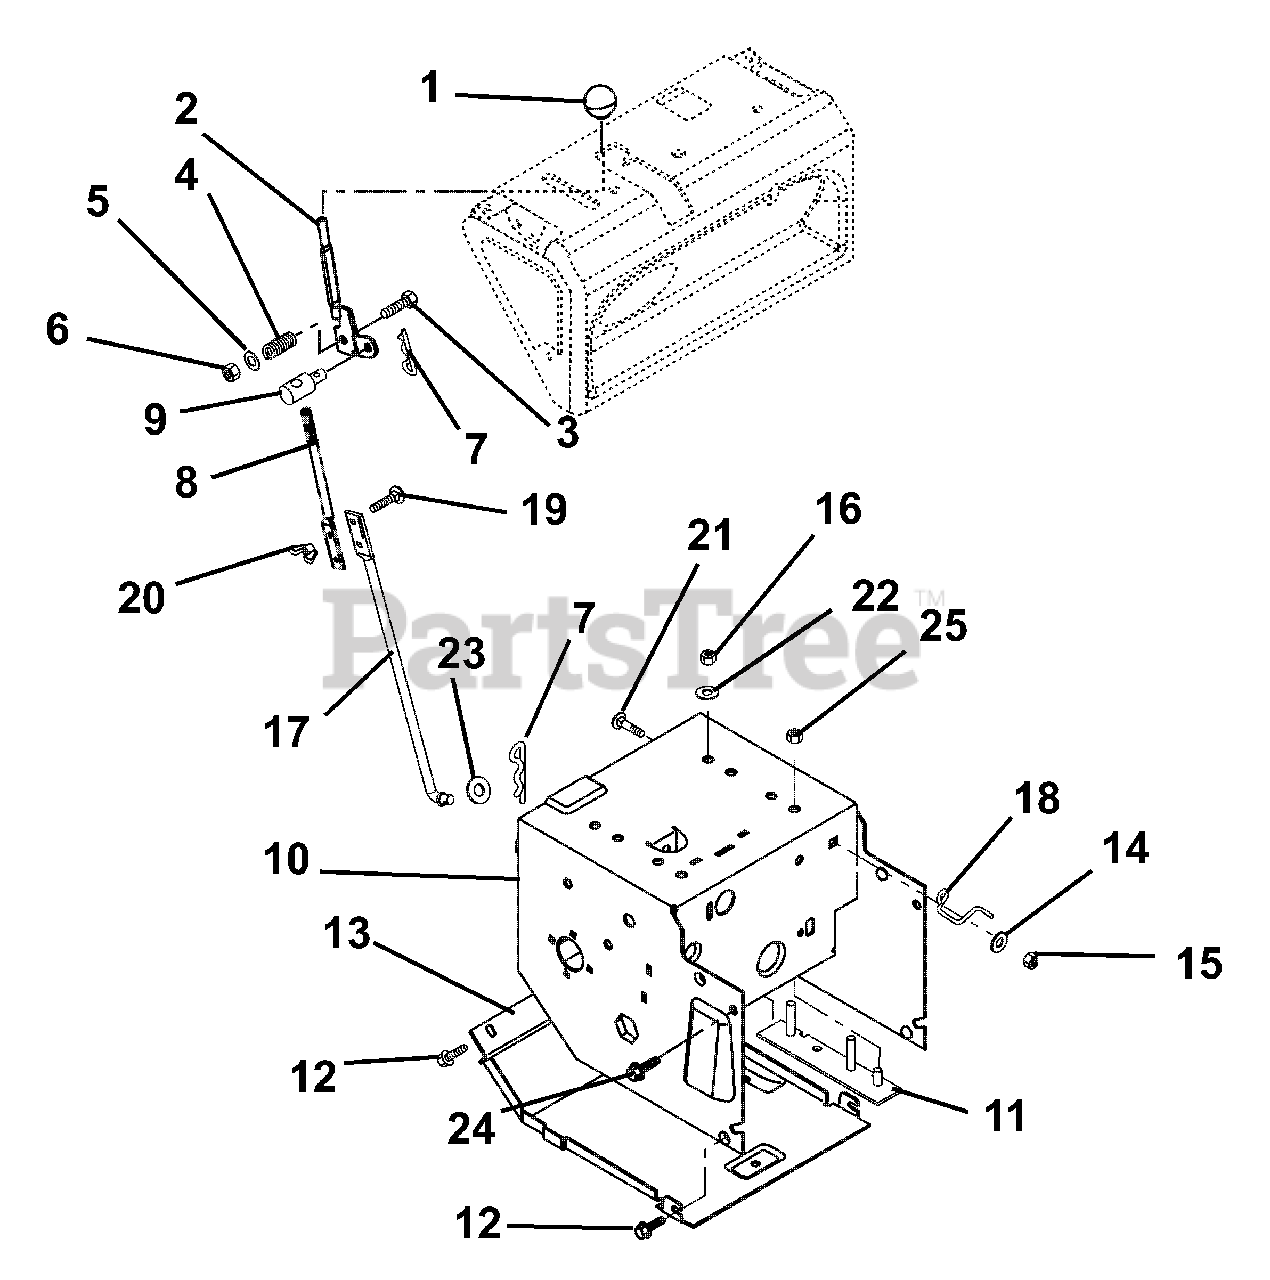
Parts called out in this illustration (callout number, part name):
1	KNOB,BALL -BLACK 1.47" .375-16
2	WMT, SHIFT LEVER
3	@BLT-RDHDSQNK .38-16X2.50 G5YZ
4	SG-COMP .125X.781X1.250
5	@WSHR-FL-STL.438X1.00X.083 YWZ
6	@NUT-LK-CTR .38-16 YWZC
7	PIN-HAIR INT .08X.18X1.18 YWZC
8	ROD, SHIFT-UPPER
9	PIVOT, ROD (TRUNNION ) .50
10	FRAME, COMPACT SNOW
11	ENGINE MOUNT, 5L,7L,8R
12	@SCR-TAP .25-20X.37 HWH YWZ TR
13	COVER BOTTOM
14	@WSHR-FL-STL.38X.875X.083 YWZC
15	@NUT-LK-CTR .31-18 YWZC
16	@NUT-HEX .31-18 YWZC
17	ROD, SHIFT-LOWER
18	FINGER, BELT
19	@BLT-RDHDSQNK .25-20X1.00 G5YZ
20	NUT-LK WING .250-20 YWZC
21	@BLT-RHDSSQNK .31-18X.75 G5YZ
22	WSHR-LK .312X.097 HVY YWZC
23	@WSHR-FL-STL.531X1.06X.095YWZC
24	@SCR-TAP .38-16X.50 HWH TR YWZ
25	@NUT-LK-NYL .312-18 YWZC
